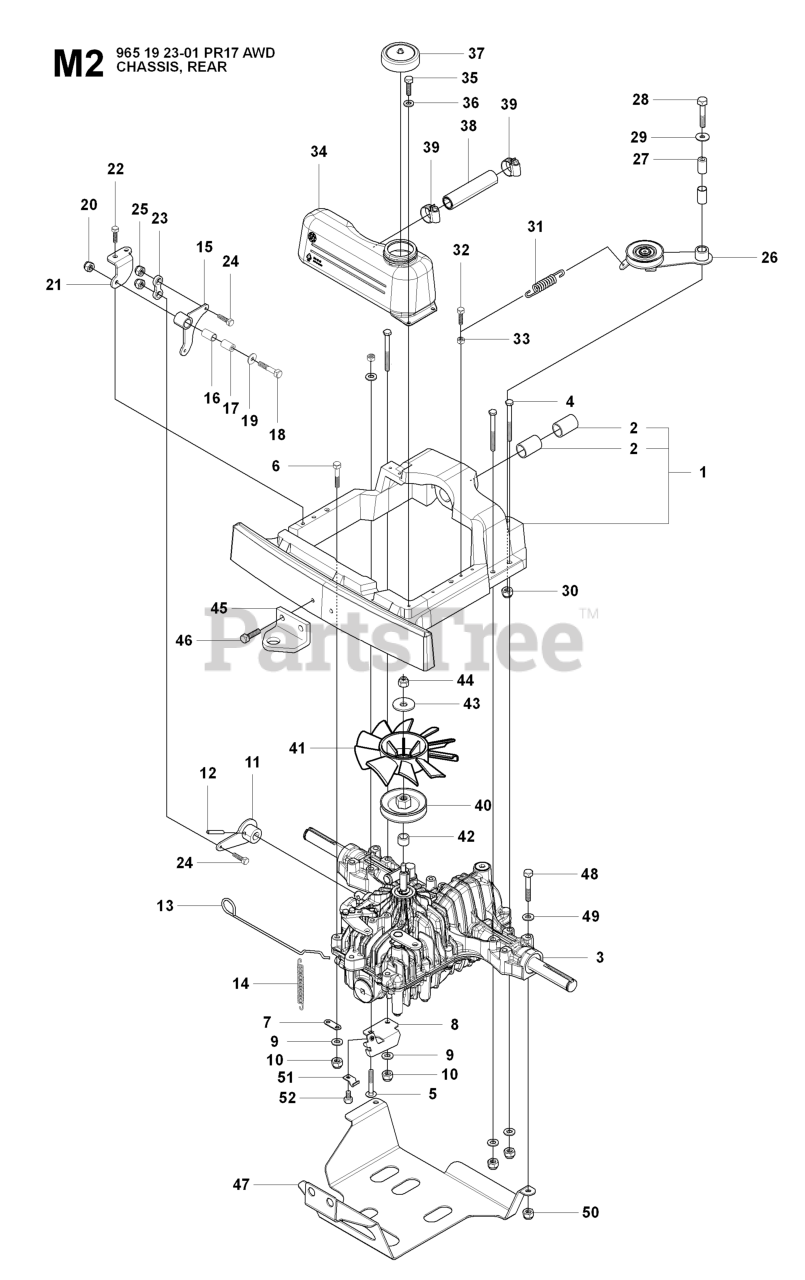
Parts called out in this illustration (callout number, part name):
9	WASHER BRB 8.4X17
10	LOCKNUT M8
18	SCREW
20	LOCKNUT M8
22	REPL BY 725 24 49-51
25	LOCKNUT M5
30	LOCKNUT M8
34	EXPANSION TANK K664
35	BOLT FLANGE - M6X20
36	WASHER - 26X6.5X1.6
46	Screw M10x25
49	WASHER BRB 8.4X17
50	LOCKNUT M8
